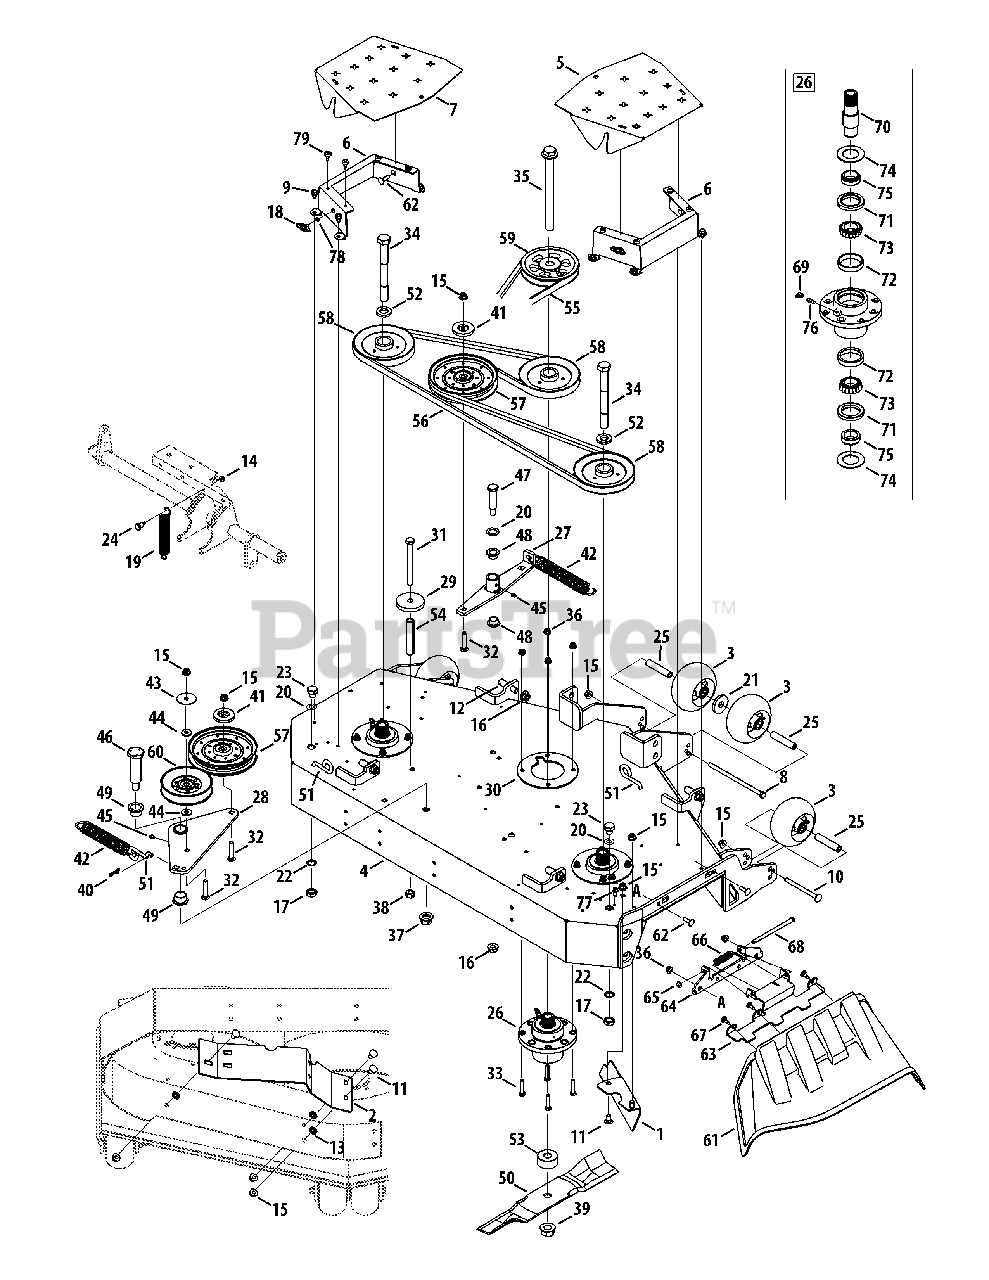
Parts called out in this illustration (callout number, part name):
2	Baffle, 60" Adjustment
3	Complete Wheel, 5.00 Dia.
5	Deck Belt Cover, RH
6	Deck Belt Cover Bracket
7	Deck Belt Cover, LH
8	Hex Cap Screw, 3/8-16 x 7.25
9	Screw, 5/16-18 x .500
10	Carriage Screw, 3/8-16 x 4.50
11	Carriage Bolt, 3/8-16 x .750
12	Pin, 1/2-13 x .625 x 1.2
13	Push Nut, 3/8
14	Nut, 1/4-20, Flangelock
15	Nut, 3/8-16, Flangelock
16	Nut, 1/2-13, Flangelock
17	Hex Nut, M16-1.5
19	Extension Spring, .969 x 6.180
20	Washer, .793 x 1.24 x .06
21	Flat Washer, .632 x 1.00 x .160
22	Lock Washer, 17 x 23.8 x 1.95
23	Plug, Screw, M16-1.5
24	Shoulder Bolt, .437 x .50, 1/4-20
25	Wheel Spacer
26	Spindle Assembly
27	Deck Idler Arm
28	Idler Assembly
29	Spacer, .5375 x 2.75 x .375
30	Spindle Support Plate
31	Hex Cap Screw, 1/2-13 x 5.00
32	Screw, 3/8-16 x 2.00
33	Bolt, 5/16-18 x 1.25
34	Hex Cap Screw, 3/4-16 x 7.00
35	Hex Cap Screw, 3/4-16 x 9.00
36	Nut, 5/16-18, Flangelock
37	Nut, 5/8-18, Flangelock
38	Nut, 1/2-13, Hexlock
39	Nut, 3/4-16, Flangelock
40	Bow Tie Cotter Pin
41	Pulley Cap
42	Extension Spring, 1.248 x 8.5
43	Washer, .406 x 1.92 x .060
44	Washer, .406 x 1.00 x .105
45	Grease Fitting
46	Shoulder Bolt, 1.0 x 3.15, 5/8-18
47	Shoulder Bolt, .750 x 2.23, 1/2-13
48	Flange Bearing, .75 x .52
49	Flange Bearing, 1.00 x .75
50	Hi-Lift Blade, 21.0
51	Spring Rod Hook
52	Spacer, .812 x .218
53	Spacer, .760 x 2.00 x .925
54	Spacer, .405 x .75 x 3.875
57	Idler Pulley
58	Spindle Pulley
59	Drive Pulley
60	Idler Pulley
61	Discharge Chute Assembly
62	Carriage Bolt, 5/16-18 x 1.00
65	Push Cap
66	Torsion Spring
67	Shoulder Screw, 1/4-20
68	Chute Rod
69	Grease Fitting, 45 degree, 1/4-28
70	Spindle Shaft
71	Seal, Oil
72	Cup Bearing
73	Cone Bearing
74	Washer, 1.50 x 2.52 x .075
75	Ring, Seal
76	Straight Adapter Fitting
77	Hex Flange Screw, 1/4-20 x .500
78	Speed Nut, .3125
79	Bumper, .62 Dia. x .3
